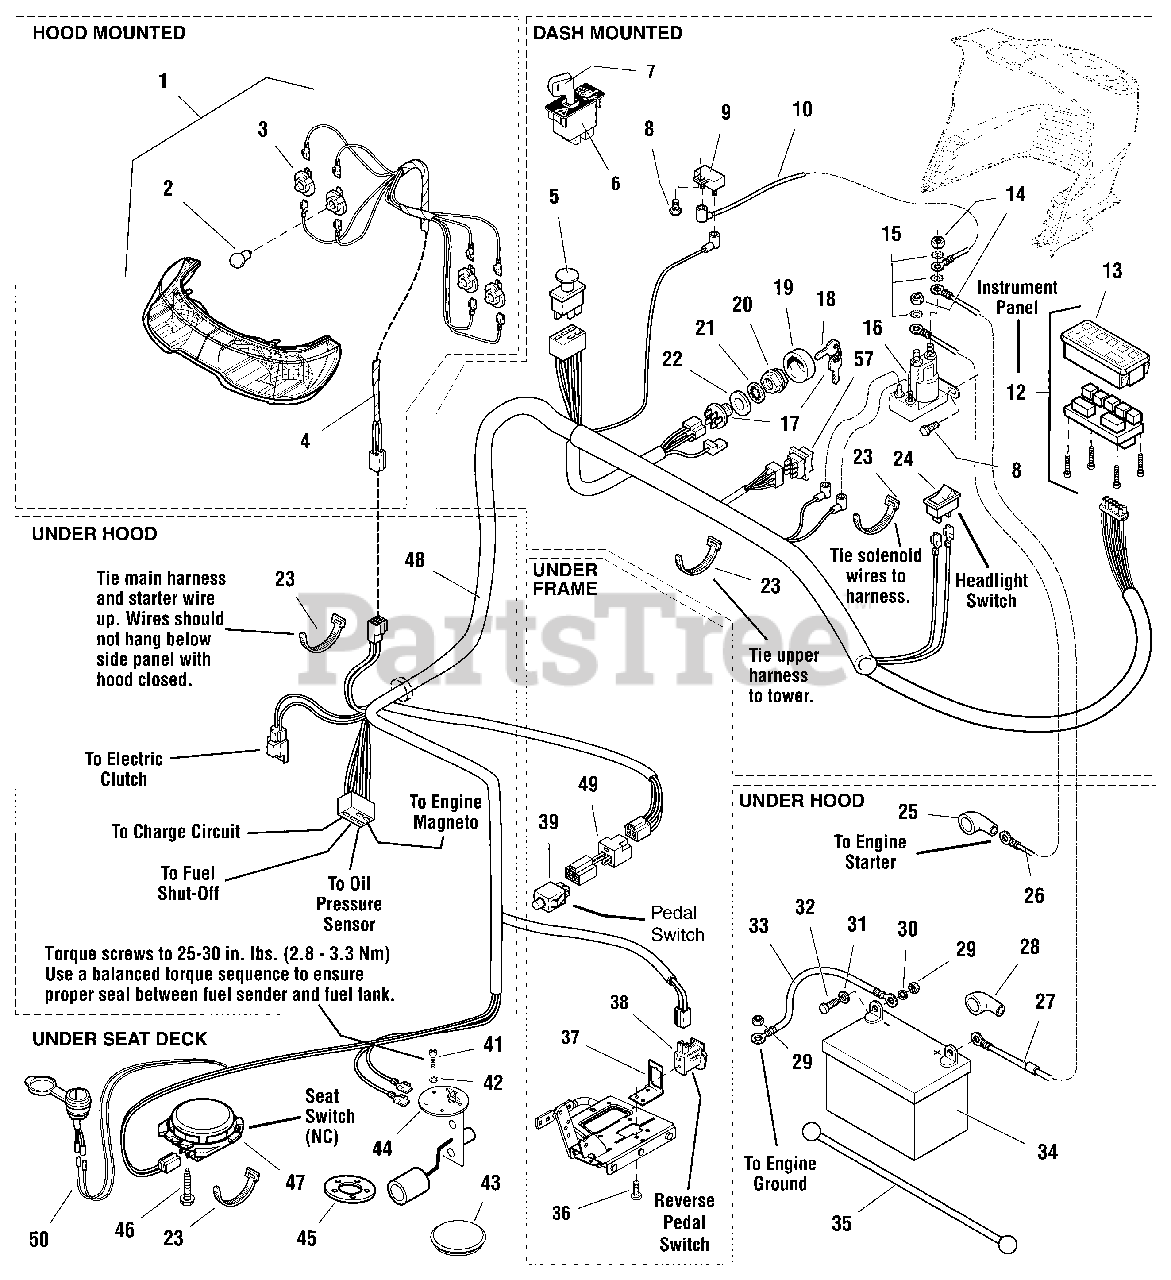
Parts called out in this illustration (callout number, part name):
1	HEADLIGHT ASSEMBLY, 4 Bulb
2	BULB, Headlight, 12.8V
3	SOCKET ASSEMBLY, Headlight, Sealed
4	HARNESS, Headlight
5	SWITCH, PTO Push/Pull Symbols
6	SWITCH, RMO Module Only
7	KEY, RMO Module Plastic
8	CAPSCREW, Hex Washer Head Taptite, 1/4-20 x 1/2, Black
9	BREAKER, Circuit, 12 Volt 20 Amps
10	WIRE, 12GA 5-15/16 Long, Red
12	PANEL, Instrument w/ Fuel Gage & Hour Meter
13	COVER, Instrument Panel
14	NUT, Hex, 5/16-24
15	LOCKWASHER, External Tooth, 5/16
16	SOLENOID
17	SWITCH ASSEMBLY, Ignition, 6 Pin INDAK
18	KEYS, Set of 2
19	COVER, For Ignition Switch, Plastic
20	NUT, Hex Flange, 5/8-32, Ignition Switch
21	LOCKWASHER, Internal Tooth, 5/8, Thin
22	WASHER, Shim
23	TIE, Strap, 7-5/16 Long
24	SWITCH, Headlights , 2 Terminal
25	BOOT, Insulator Cable Terminal, 1-15/16 Long, Red
26	CABLE, #6 x 25" Long, Ring Terminals
27	CABLE, #6 x 8" Long, Ring Terminals
28	BOOT, Insulator Battery Terminal
29	NUT, Hex, 1/4-20
30	LOCKWASHER, 1/4
31	WASHER, 1/4
32	CAPSCREW, Hex Head, 1/4-20 x 3/4
33	CABLE, #6 x 26 Long, Ring Terminal
35	STRAP, Battery, 14 Long, Rubber
36	CAPSCREW, Hex Head Taptite, 1/4-20 x 3/8
37	BRACKET, Switch Mount
38	SWITCH, Reverse Pedal
39	SWITCH, Push Button, Foot Pedal
41	SCREW, Pan Head Torx, #10-32 x 1/2
42	LOCKWASHER, 3/16 #10
43	PLUG, Hole 3", Round
44	SENDER, Fuel Tank
45	GASKET
46	CAPSCREW, Hex Washer Head Plastite, 1/4 x 1/2
47	SWITCH, Seat, Grey, NC
48	HARNESS, Wiring
49	WIRING ASSEMBLY, All Conditions Shutdown
50	12-VOLT OUTLET
57	SWITCH, EHOC
